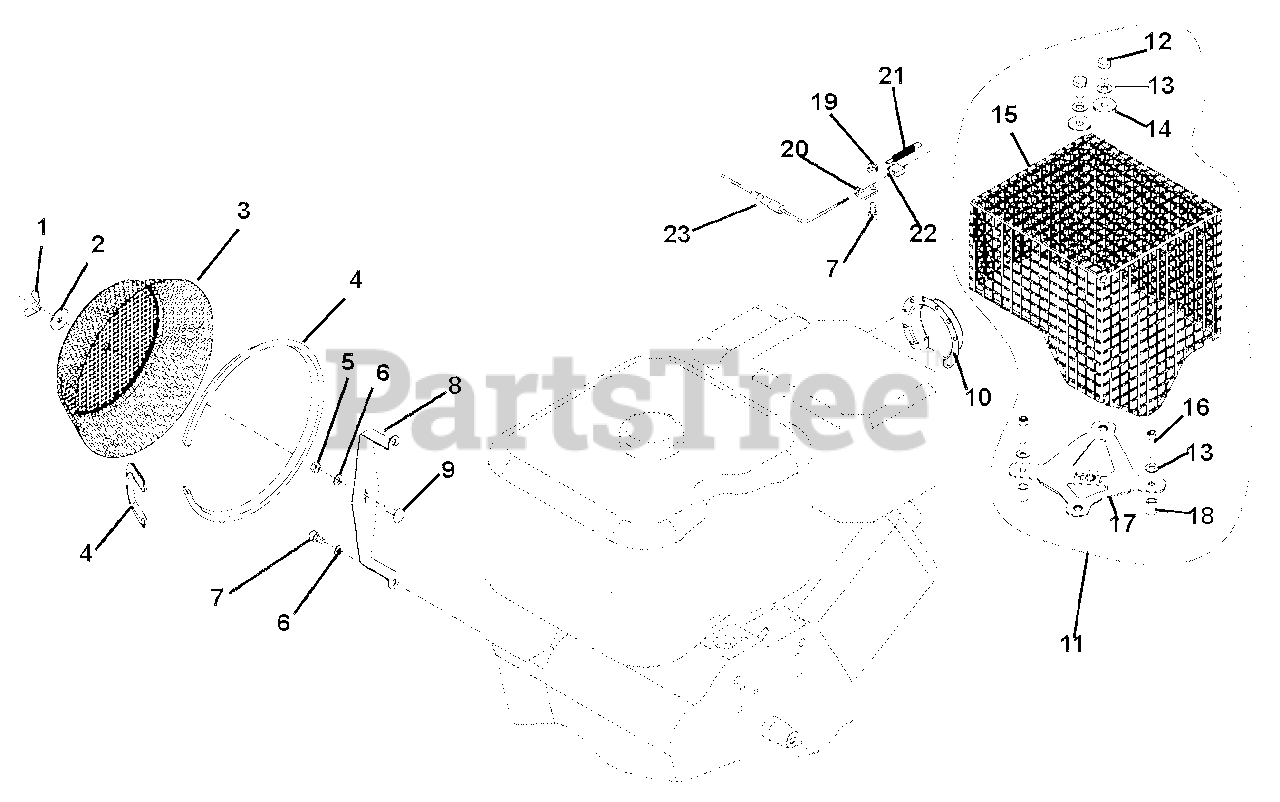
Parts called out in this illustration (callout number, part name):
1	Nut, Wing M6
2	Washer, 7 x 25 x 1.8
4	Edge Guard
5	Nut, Hex M6
6	Washer, 6.1/12.2 x 1.2
7	Screw, M6 x 12
9	Screw, M6 x 20
10	Deflector
11	HEat Protector Assembly (contains 12 - 18)
12	Bolt, Hex M8 x 16
13	Washer, 8.2/16.2 x 1.4
14	Washer, 8.4 x 25 x 2
15	Heatr Protector
16	Screw, M6 x 25
18	Distance Brush
19	Nut, Lock M6
20	Fish Plate
21	Spring, Tension 1.2/10.8 x 62
22	Nipple, 2mm
23	Cable, Gas
